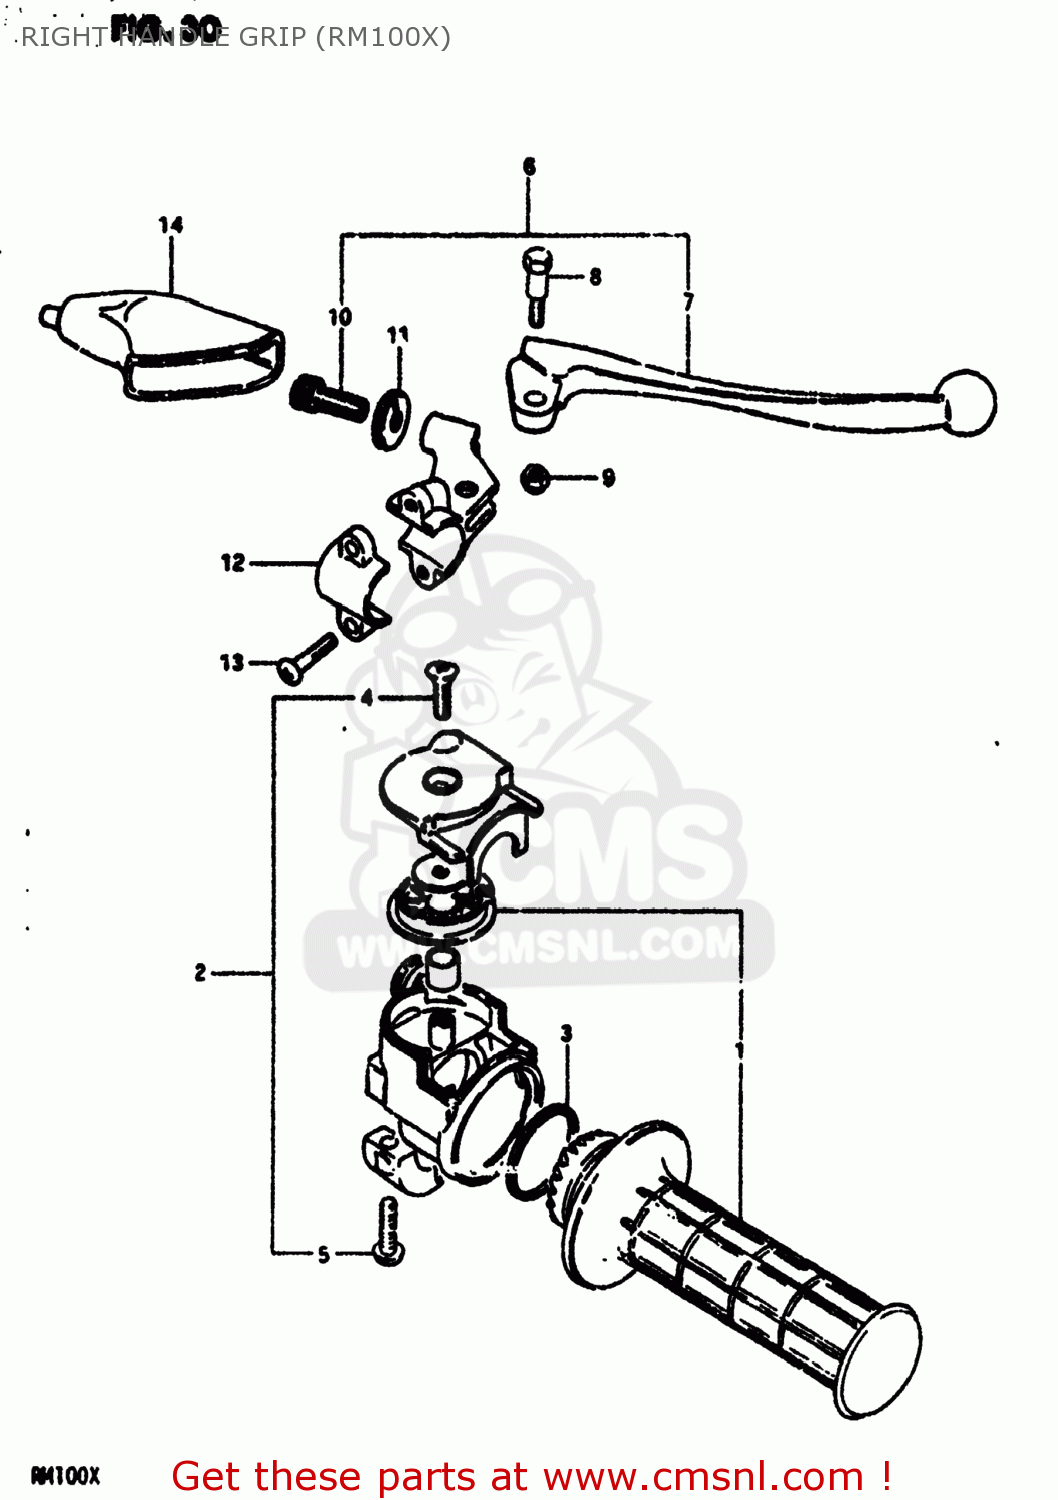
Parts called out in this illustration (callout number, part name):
1	GRIP SET,THROTTLE
2	CASE ASSY,THROTTLE
3	V-RING,THROTTLE GRIP
4	SCREW
5	SCREW
6	LEVER ASSEMBLY,BRAKE
7	LEVER,BRAKE
8	BOLT,LEVER
9	NUT 6MM
10	ADJUSTER,CABLE
11	NUT,CABLE ADJUSTER
12	BRACKET,LEVER
13	SCREW
14	COVER,CLUTCH LEVER
